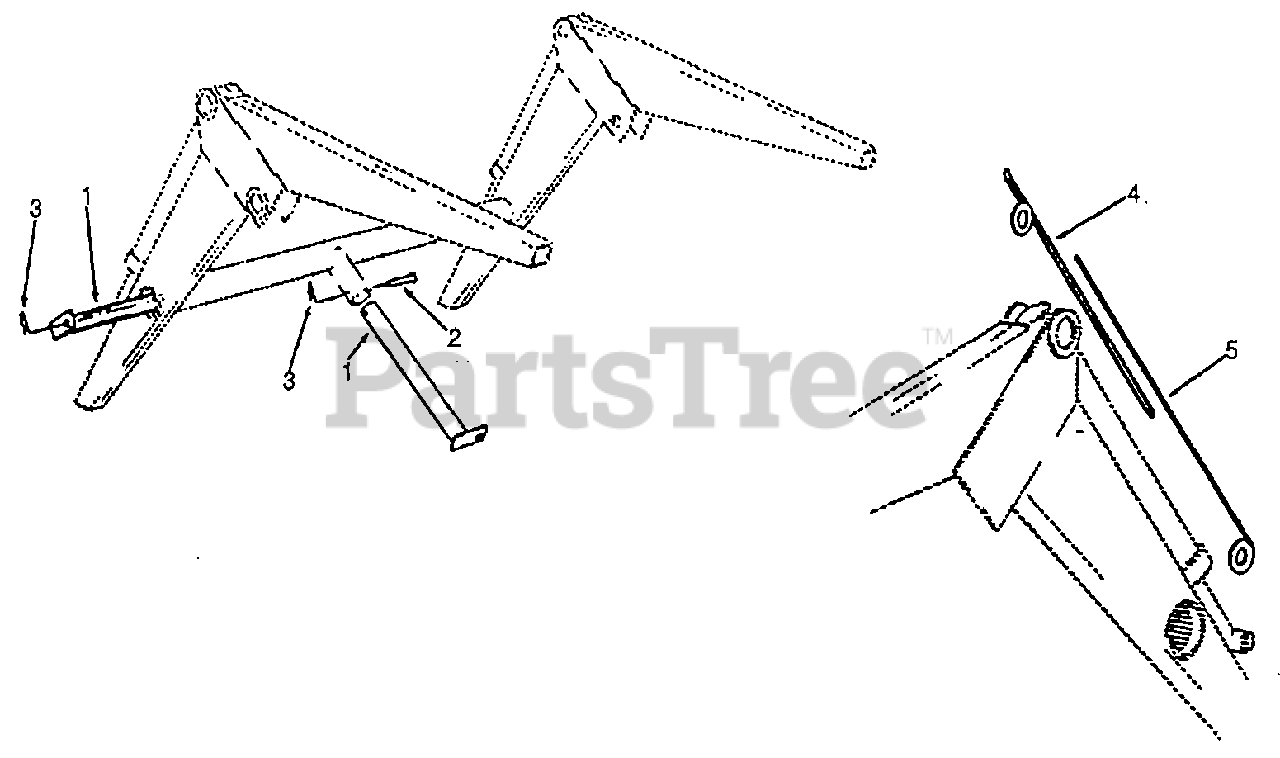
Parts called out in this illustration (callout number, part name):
1	LEG, PARKING
2	PIN (1/2X2-5/8") (NOT AVAILABLE)
4	TUBE, LEVEL INDICATOR
5	ROD, LEVEL INDICATOR
